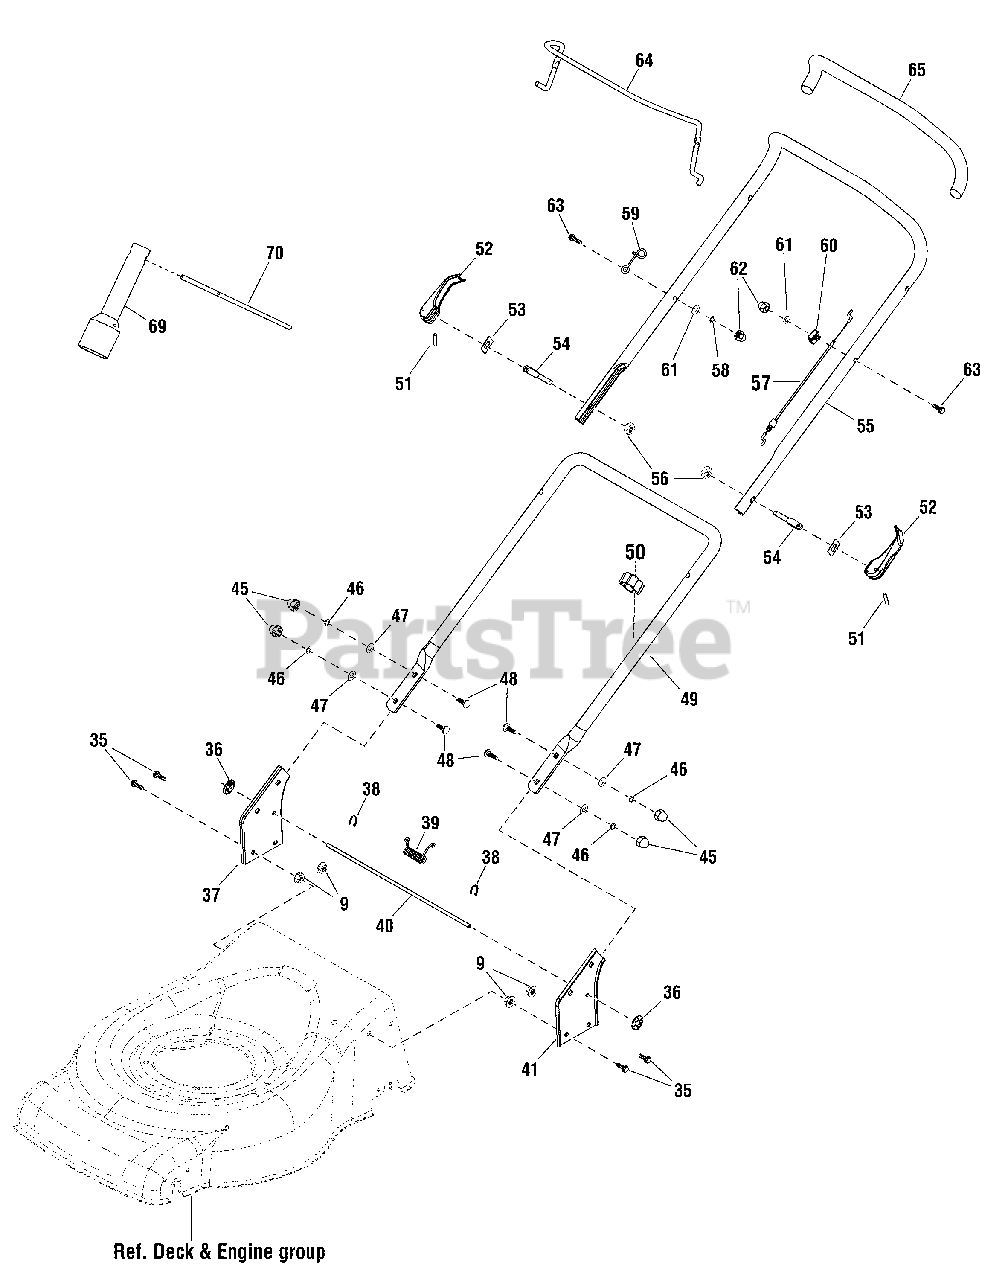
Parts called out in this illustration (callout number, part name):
9	* NUT, Hex Lock
35	* BOLT, Hex
36	CLAMP, Wheel
37	SUPPORT, Handle, RH
38	WASHER, Split
39	SPRING, Rear Cover
41	SUPPORT, Handle, LH
46	WASHER, Spring
47	* WASHER, Flat
48	BOLT, Cup Head Square Neck
49	HANDLE, Lower
50	* CLAMP, Cable
52	LEVER, Locking
53	PLATE, Pressing
55	HANDLE, Upper
56	* NUT, Hex Lock
57	CABLE, Brake
58	WASHER, Spring
59	CABLE HOOK
60	CLAMP, Cable
61	* WASHER, Flat
63	* BOLT, Hex
64	BAIL, Brake
69	SLEEVE WRENCH
70	HANDLE, Wrench
